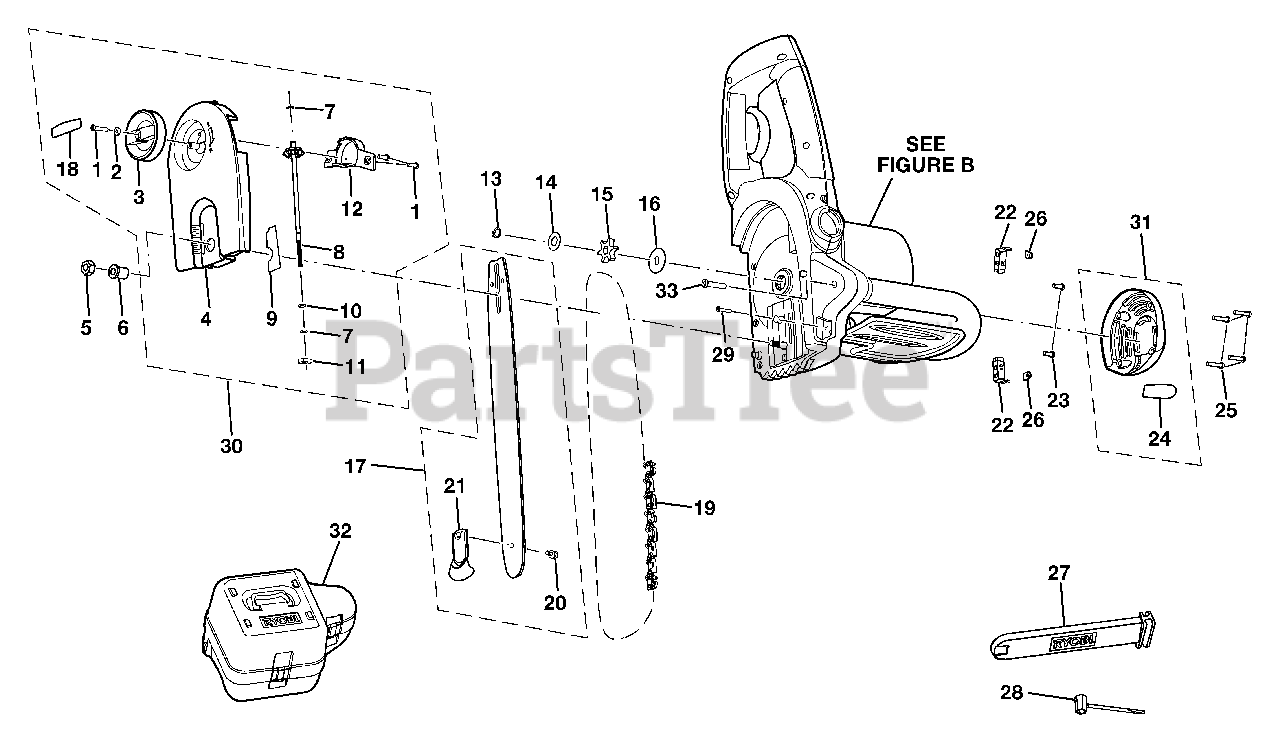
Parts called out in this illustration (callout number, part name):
1	SCREW (M4 X 12 mm PAN HD)
2	FLAT WASHER (OD10 X ID4.2 X 1.0)
3	BAR COVER KNOB WITH BEVEL GEAR
4	BAR COVER
5	GUIDE BAR NUT
6	GUIDE BAR NUT BUSHING
8	ADJUST SCREW ASSEMBLY
9	RUBBER SEAL
10	WASHER (OD9.5 X ID5.3 X 1)
11	GUIDE BAR ADJUST PLATE
12	COVER PLATE
13	C-RING (1 mm)
17	SAW BAR ASSEMBLY (18 in.)
18	CHAIN TENSIONER LABEL
19	SAW CHAIN ASSEMBLY
20	SAFE-T-TIP (SCREW AND WASHER)
21	CHAIN TIP
22	BRUSH ASSEMBLY
23	SCREW (M8 X 1/2 in. PAN HD.)
24	LOGO LABEL
25	SCREW (M4 X 16 mm PAN HD.)
26	BRUSH CLAMP
27	BLADE GUARD (SCABBARD)
29	SCREW (M4 X 22 mm PAN HD.)
30	BAR COVER W/ LABEL ASSEMBLY
31	MOTOR END CAP W/ LABEL ASSEMBLY
32	CARRYING CASE
33	SCREW (M4.5 X 22 mm PAN HD.)
